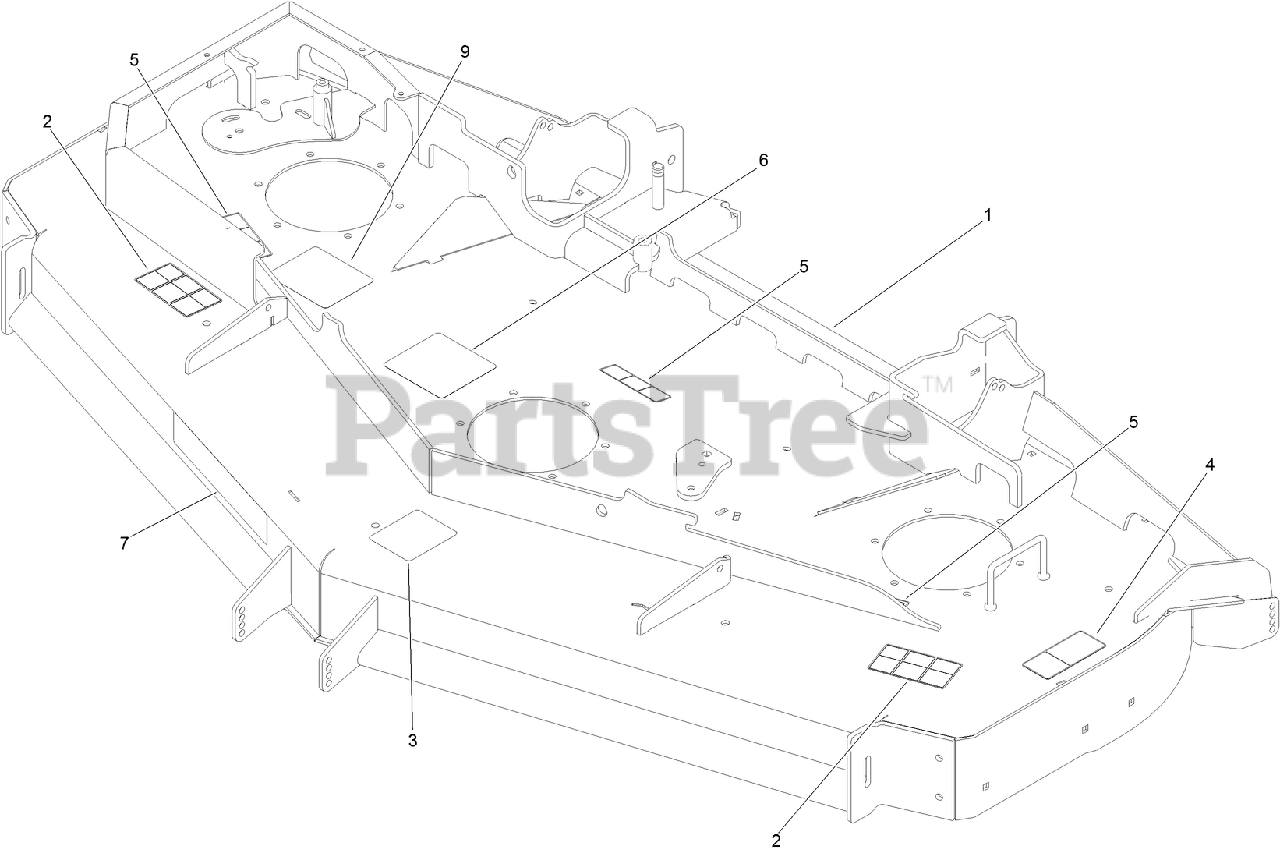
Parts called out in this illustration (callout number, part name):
1	DECK DECAL ASM
2	DECAL-DANGER
3	DECAL-ROLLER, ANTI-SCALP
4	DECAL-TORQUE, BLADE BOLT
5	DECAL-COVER, MISSING
6	DECAL-ROUTING, DECK BELT
9	DECAL-SPINDLE, COUNTER ROTATING
